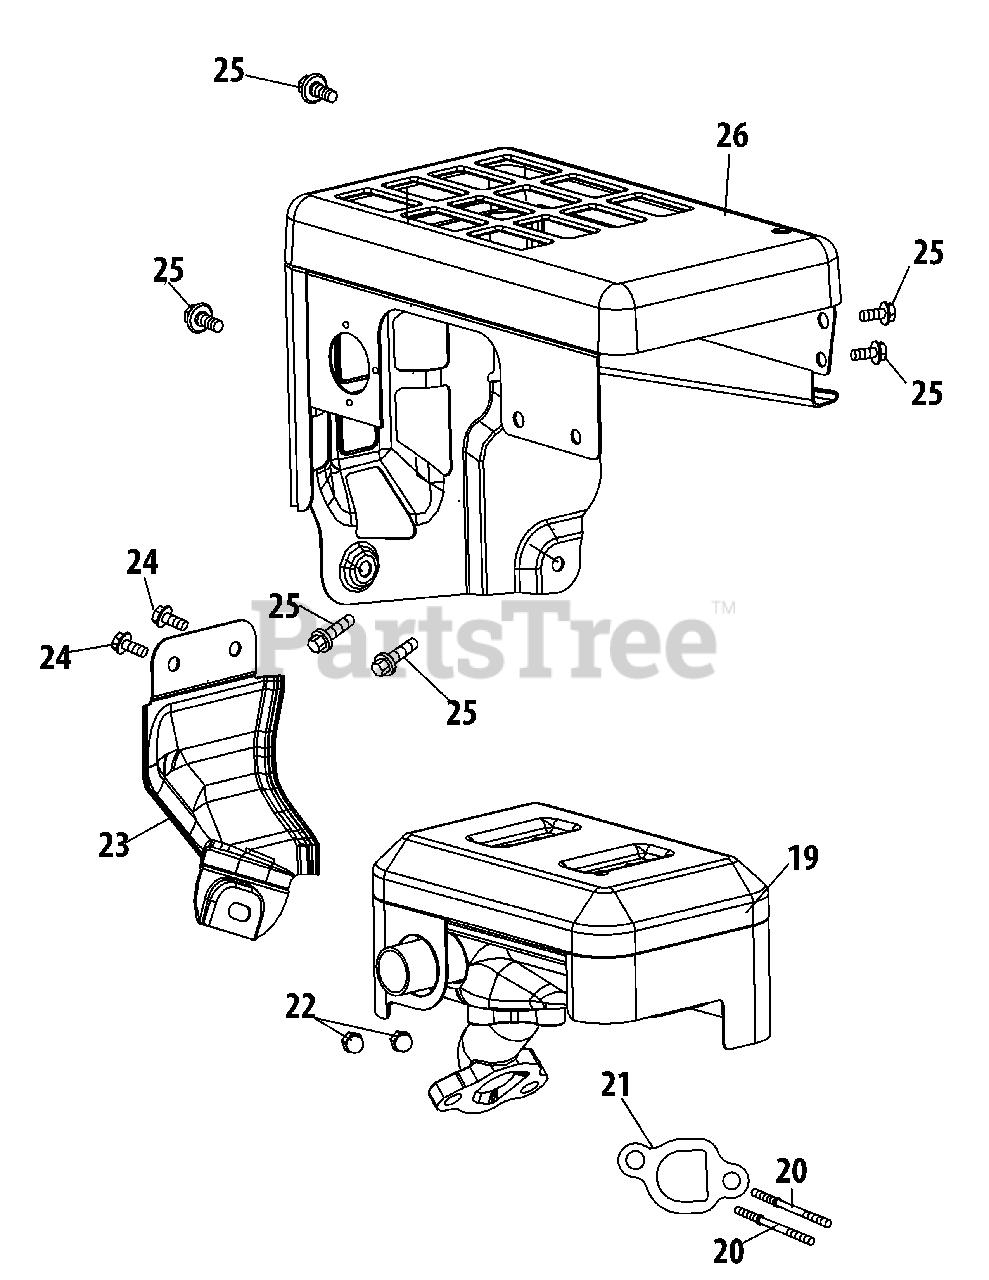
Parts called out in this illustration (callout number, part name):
19	Muffler Assembly
20	Stud M8×36
20	Muffler Stud Assembly
21	Exhaust Pipe Gasket
22	Nut, M8
23	Exhaust Pipe Shield
24	Bolt M6×10
25	Bolt M6×12
26	Muffler Shield
